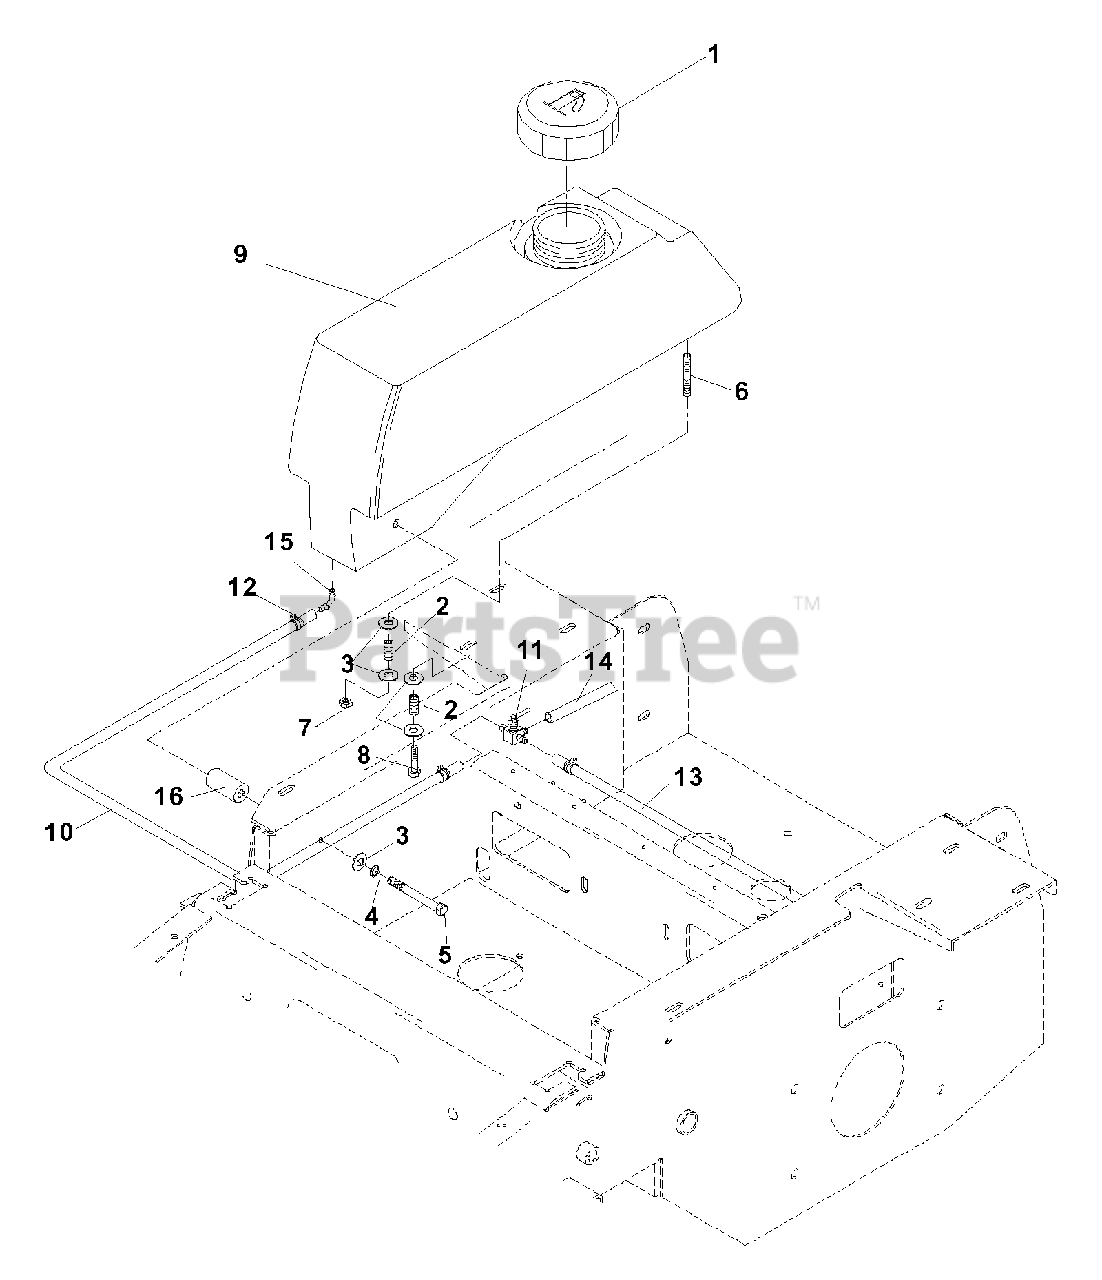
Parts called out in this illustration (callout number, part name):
1	CAP, FUEL
3	WASHER, 5/16
4	LOCKWASHER, 5/16
5	HCS, 5/16C x 4
7	NUT, 5/16C, CENTERLOCK
8	HCS, 5/16C x 1
9	FUEL TANK, RIGHT
9	FUEL TANK, LEFT
11	VALVE, FUEL
12	CLAMP, HOSE
14	FUEL LINE, 13"
16	SPACER, TANK
